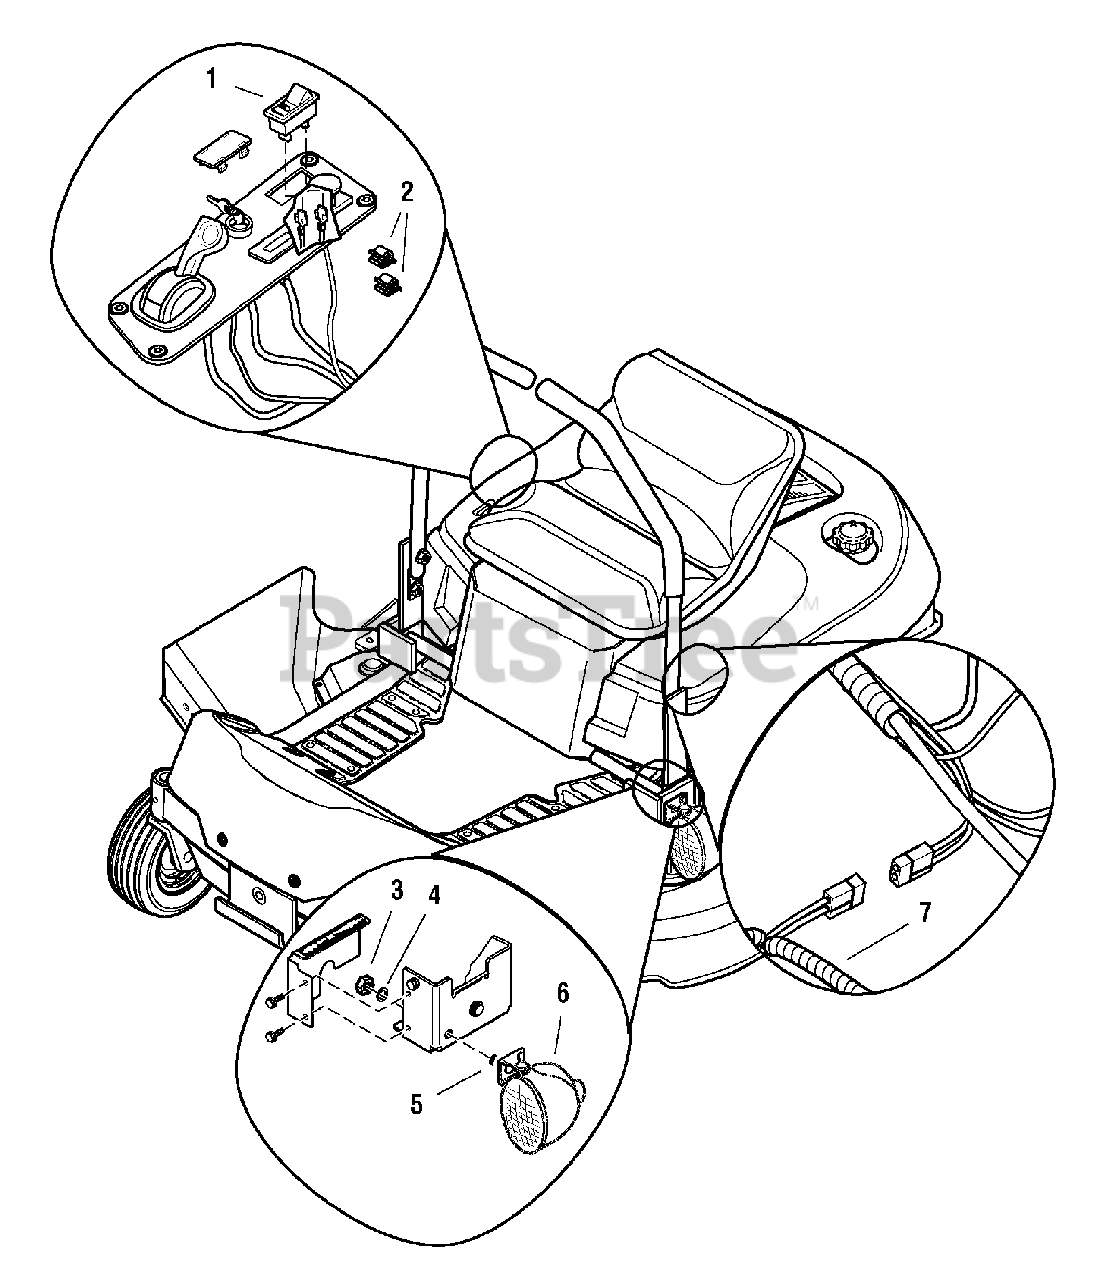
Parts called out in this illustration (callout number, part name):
1	NUT, Hex Lock with Nylon Insert, 5/16-18
2	WASHER, Lock Helical Spring
3	BOLT, Carriage, 5/16 - 18 x 1
4	HEADLIGHT ASSEMBLY
5	SWITCH, Headlights
6	CLIP, Wire
7	HARNESS, Wire
